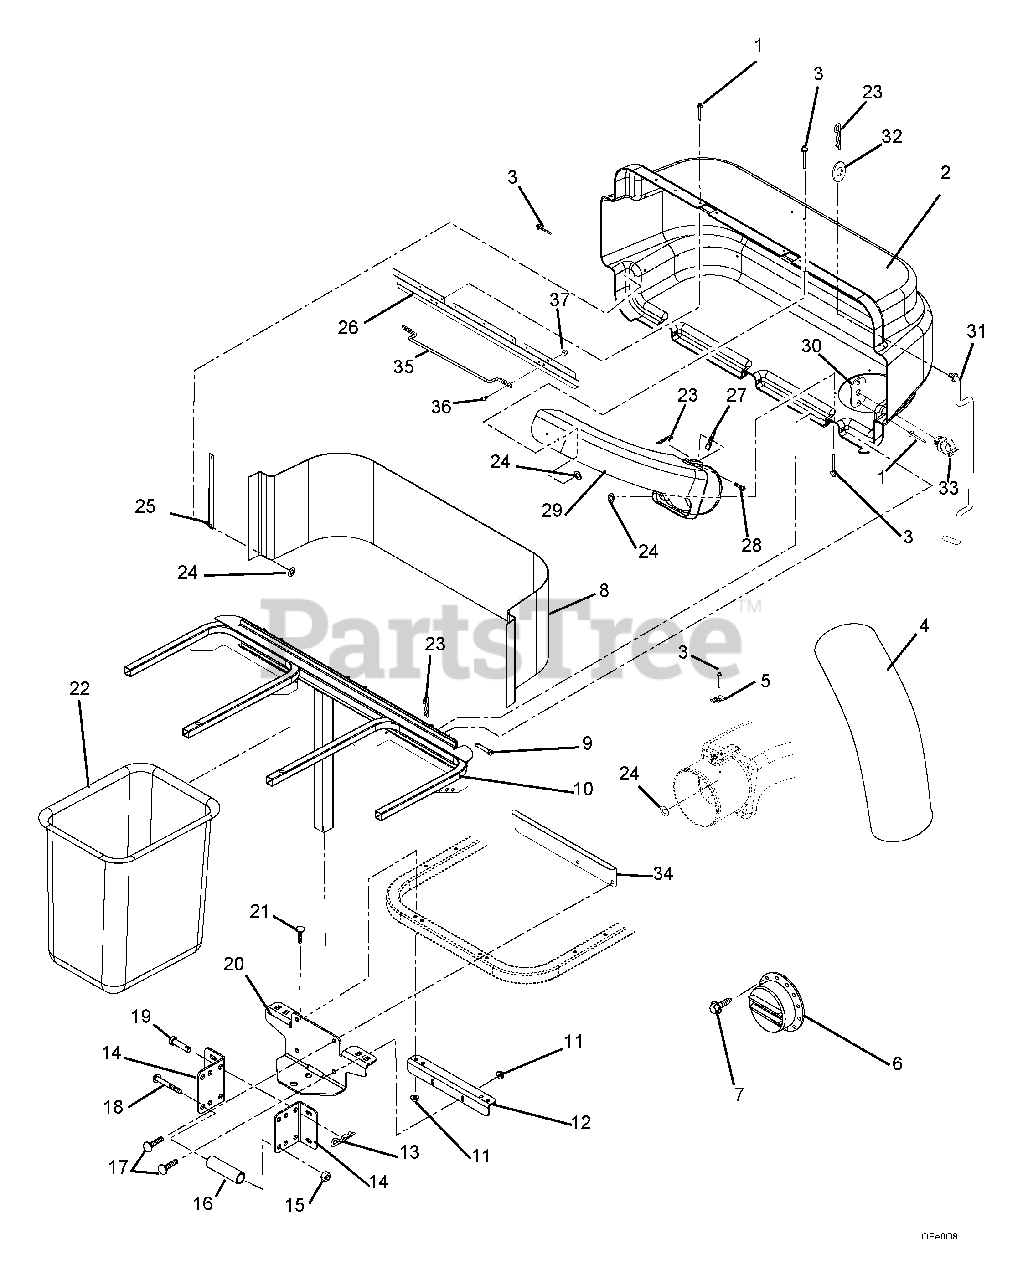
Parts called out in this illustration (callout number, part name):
1	RVT-POP .187X.402 DOME ST
2	BAGGER COVER W/DECAL
3	RVT-POP .187X.375
4	HOSE, FLEXIBLE-47"
5	THUMB LATCH
6	DEFLECTOR,EXHAUST
7	SCR-TAP 8-32X.38 SL HWH YWZC
8	SCREEN, BAGGER
9	PIN-CLEV .371X3.25 YWZC
10	WMT,BAGGER FRAME
11	@NUT-LK-TOP-FLG .38-16 YWZC
12	BRKT,ANGLE
13	PIN-HAIR-EXT .12X.31X2.37 YWZC
14	BKT,BAGGER MOUNT
15	@NUT-LK-TOP-FLG .50-13 YWZC
16	SPACER, PIVOT .500X.750X1.805
17	@BLT-RDHDSQNK .38-16X1.25 G5YZ
18	@BLT-HEX .50-13X3.00 GR5 YWZC
19	PIN-CLEV .494X2.50 BRIGHT ZINC
20	TRAILER HITCH W/DECALS
21	@BLT-RDHDSQNK .38-16X2.50 G5YZ
22	GRASS BAGGER BASKET
23	PIN-HAIR, ENDRIES #25 YWZC
24	@WSHR-FL-STL.219X.50X.049 YWZC
25	STRAP,COVER
26	LATCH, BAGGER (ZOOM)
27	INDICATOR, FLOW
28	PIN-CLEV .309 X 1.625 YWZC
29	BOOT,UPPER
30	PLATE, ROD CLIP
31	PROP-ROD, BAGGER
32	@WSHR-FL-STL.406X.812X.065 YWZ
33	CLIP-.38
34	DEFLECTOR, EXHAUST
35	BAGGER HANDLE
36	@BLT-RDHDSQNK .25-20X.75 G5YZ
37	@NUT-LK-TOP-FLG .25-20 YWZC
